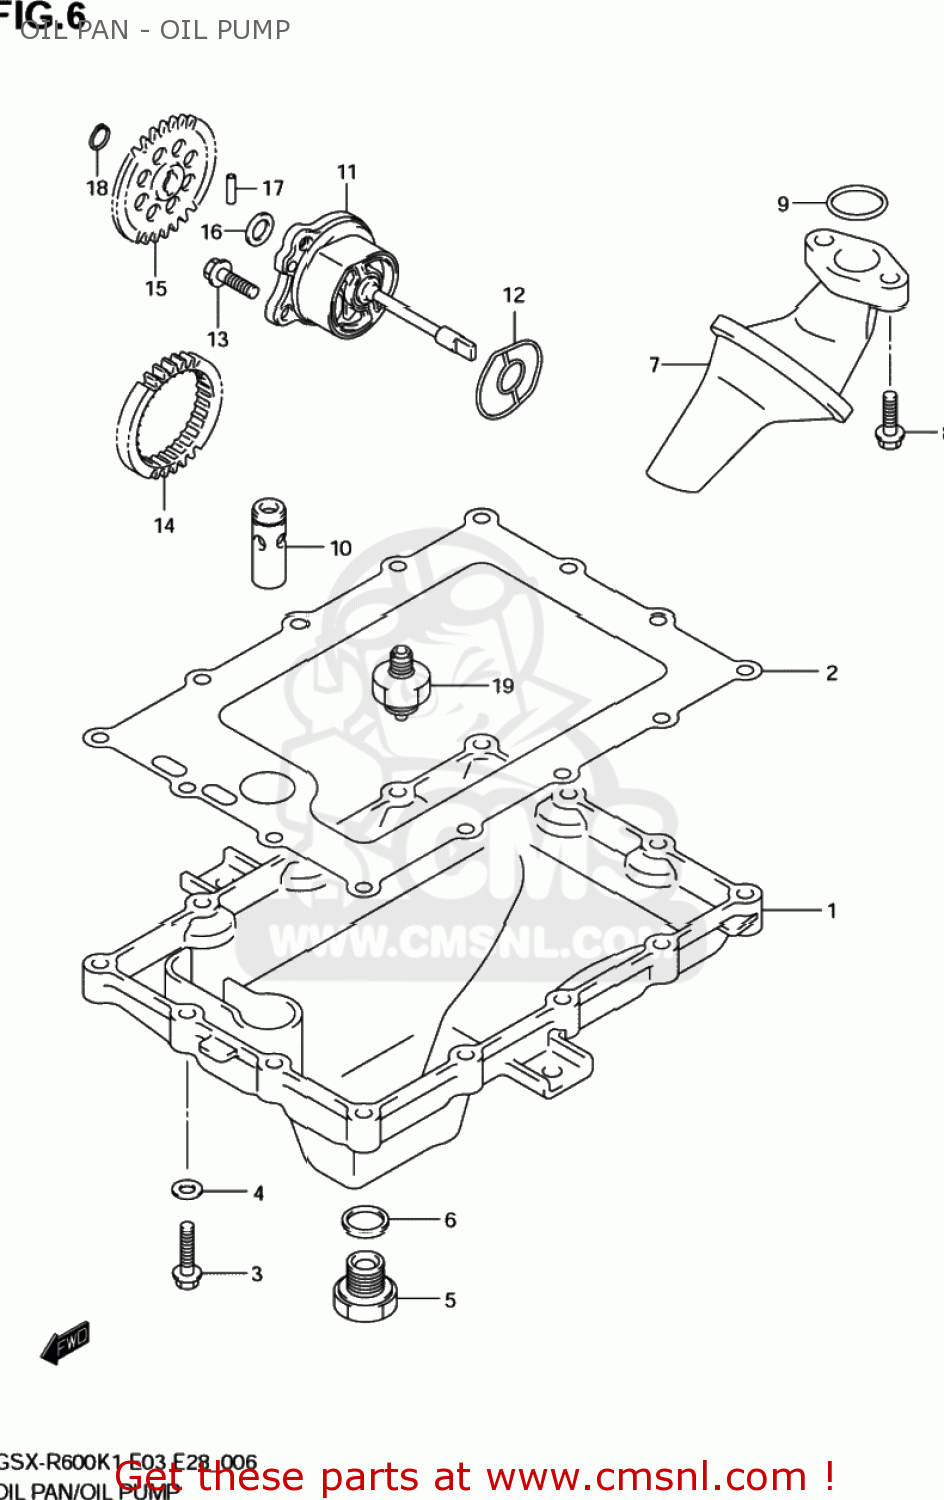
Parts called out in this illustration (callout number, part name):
1	PAN,OIL
2	GASKET,OIL PAN (NAS)
3	BOLT(6X25)
4	GASKET(5.8X13X1.2) (NAS)
5	PLUG(14X20)
6	GASKET(13.8X18.8X4.8) (NAS)
7	STRAINER ASSY,ENGINE OIL
8	BOLT
9	O RING(D:2.62,ID:20.3)
10	VALVE ASSY,OIL RELIEF(7K)
11	PUMP ASSY,ENGINE OIL
12	O RING,OIL PUMP
13	SCREW
14	GEAR,OIL PUMP DRIVE
15	GEAR,OIL PUMP DRIVEN
16	SHIM(10X18X0.5)
17	PIN(4X15.8)
18	CIRCLIP,10MM
19	SWITCH ASSY,OIL PRESSURE
